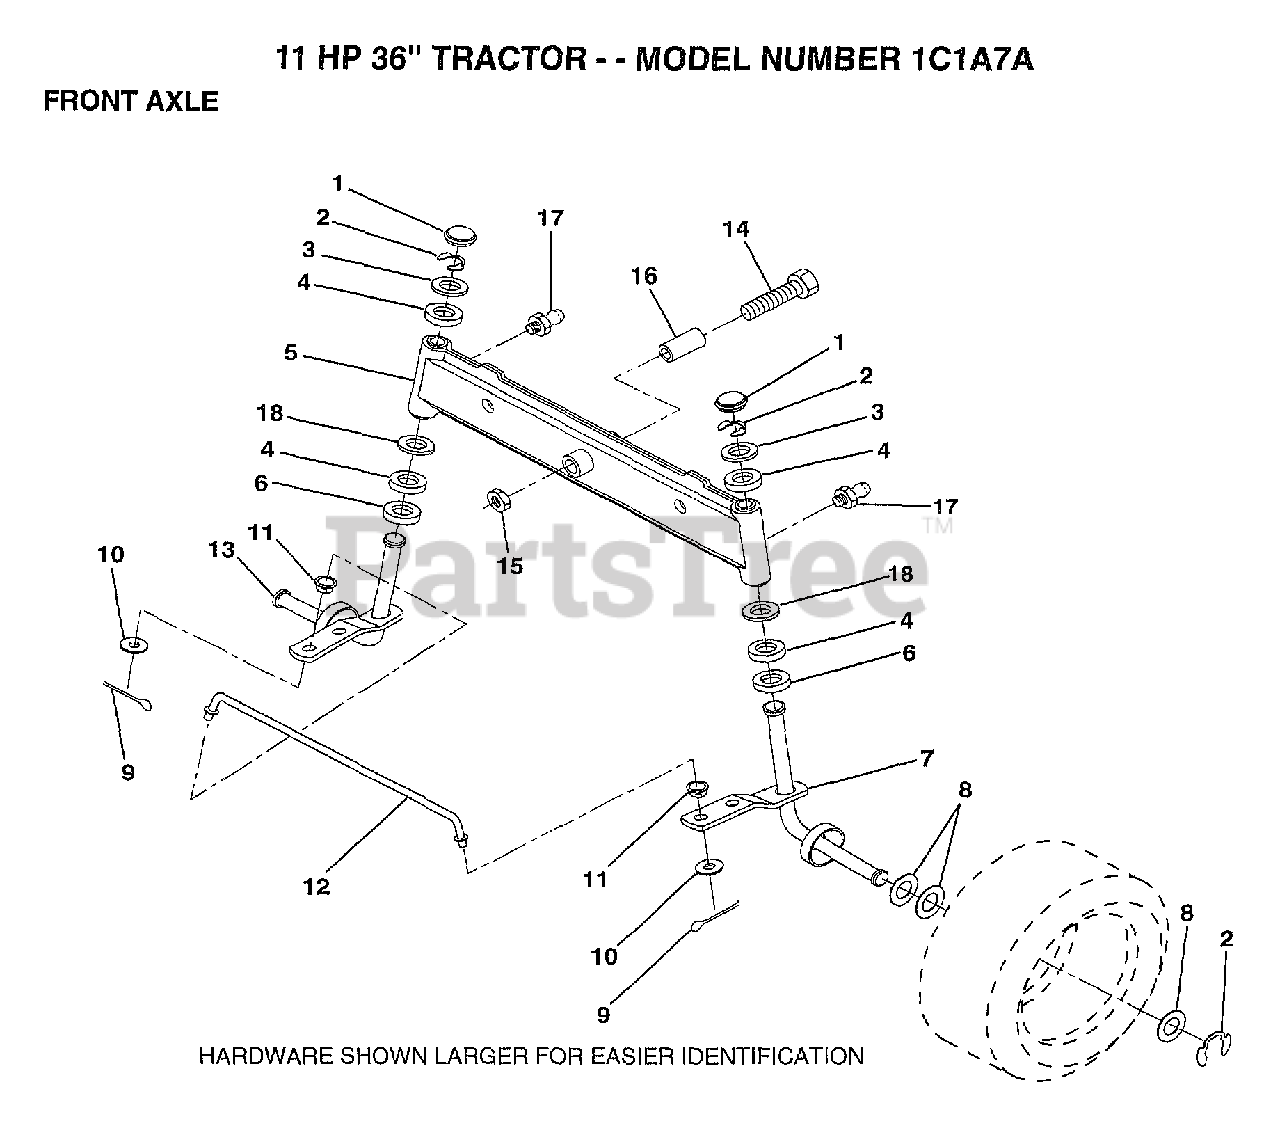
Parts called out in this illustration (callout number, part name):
1	CAP
2	RING
3	WASHER
4	COL. SRTG. BEAR.
5	AXLE ASM FRONT
6	WASHER .T
7	SPINDLE ASM RH
8	WASHER
9	COTTER PIN
10	WASHER
11	BUSHING.DRAGLINK
12	TIE ROD
13	SPINDLE ASM LH
14	BOLT HEX 5/8-11
15	"NUT-LOC,FLANGE LT"
16	BEARING
17	ZERK M
18	WASHER
